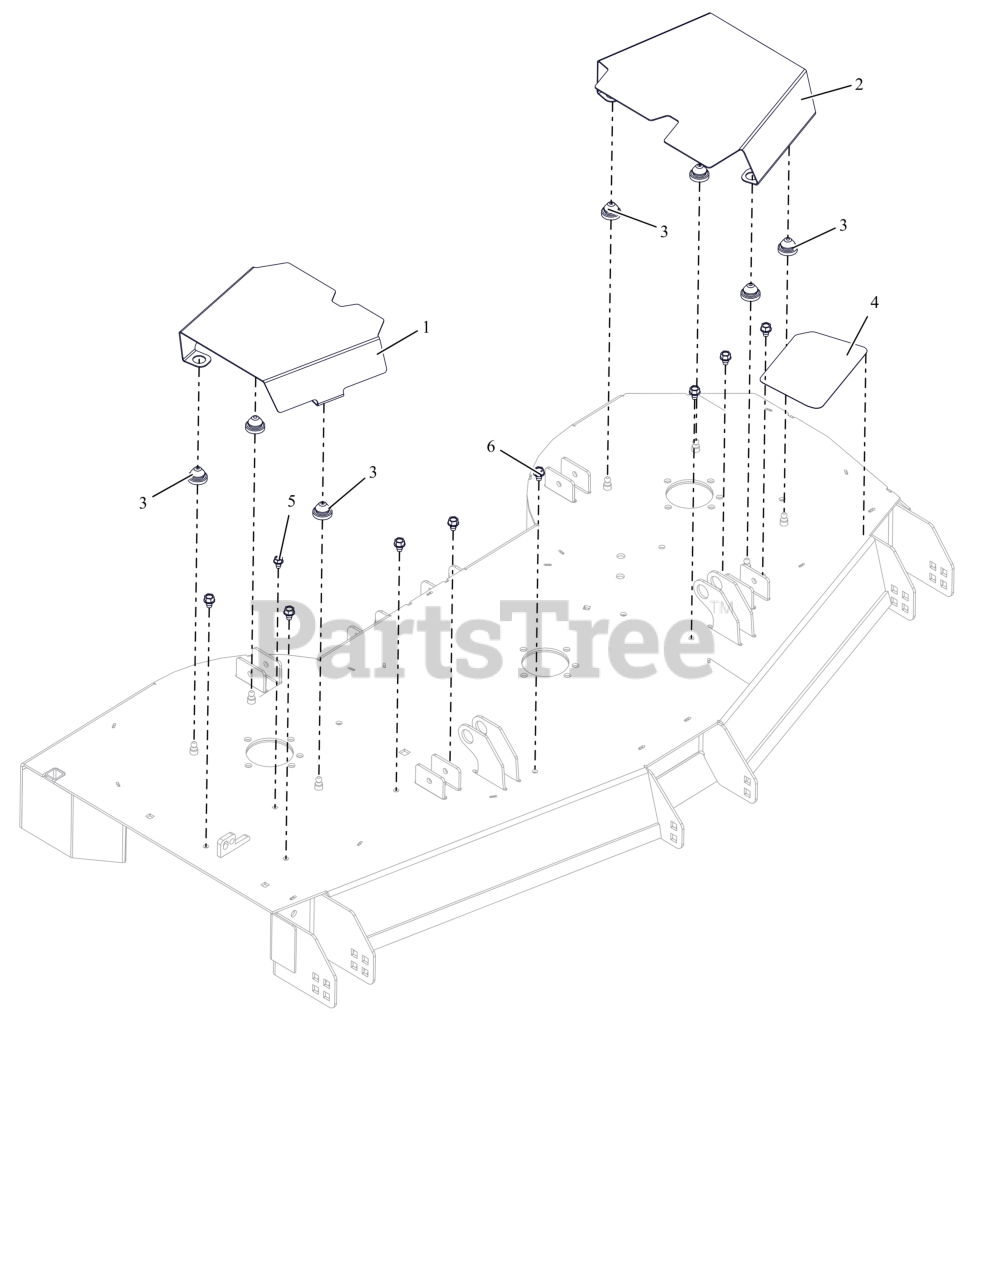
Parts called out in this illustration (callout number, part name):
1	COVER- BELT 60" RIGHT
2	COVER- BELT 60" LEFT
3	COUPLING, RUBBER PUSH-IN
4	GRIP, STEP ANTI SKID HD XF3
5	SCR,TAP .312-18X.50 HWH TR ZCC
6	SCR,TAP .375-16X.50 HWH TR ZCC
